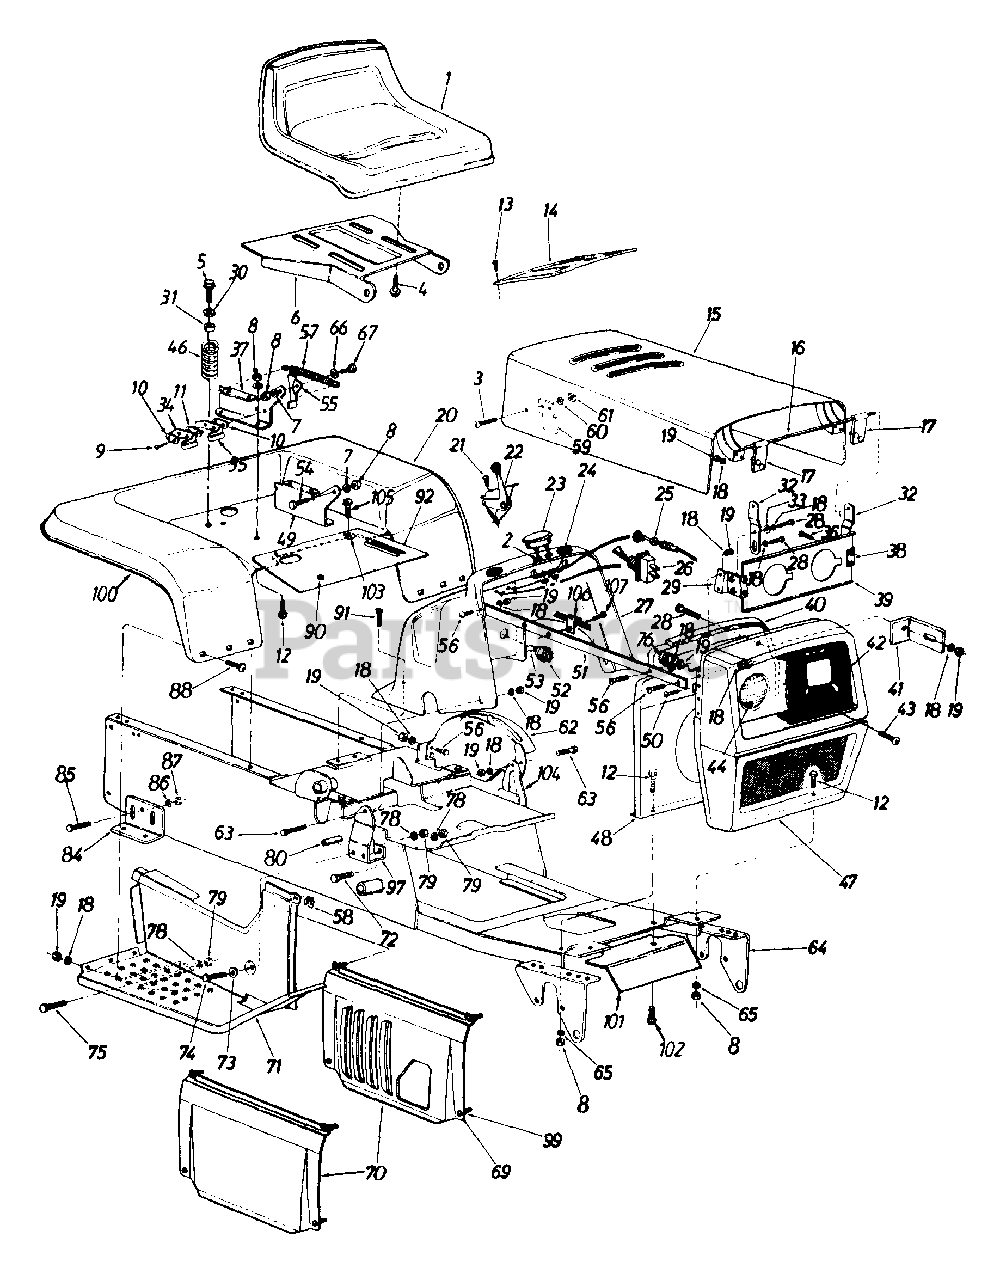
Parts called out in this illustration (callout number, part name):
2	L-Wash. .190" I.D.
3	Truss Hd. Mach. Scr. #10-24 x .38" Lg.
4	Hex Wash. Hd. Self-Tap Scr. 5/16-18 x .75" Lg.
5	Hex Wash. Hd. Tap Scr. 5/16-18 x .75" Lg.
6	Seat Pivot Bracket
7	L-Wash. 5/16" I.D.
8	Hex Nut 5/16-18 Thd.
9	Hex Wash. Hd. AB-Tap Scr. #8 x .5" Lg.
10	Insulator Plate
11	Insulator Boss Plate
12	Hex Bolt 5/16-18 x .75" Lg.
13	Self-Tap Oval Hd. Scr. 1/2" Lg.
14	Dash Panel Cover
15	Hood Ass'y.
17	Hood Hinge Ass'y.
18	L-Wash. 1/4" I.D.
19	Hex Nut 1/4-20 Thd.
20	Rear Fender
22	Throttle Control
23	Ammeter
24	Rubber Bumper
25	Choke Control
26	Light Switch
28	Hex Bolt 1/4-20 x .62" Lg.
29	Hood Support Brkt. Ass'y. - R.H.
30	Fl-Wash. .344" I.D. x .875"
34	Safety Switch
35	Safety Switch
36	Hex Bolt 1/4-20 x .38" Lg.
38	Hood Support Brkt. Ass'y. - L.H.
41	Heat Shield Brkt.
42	Head Lamp Bezel
43	Truss Mach. Scr. #10-24 x .50" Lg.
44	Head Lamp
46	Compression Spring 4.5" Lg.
50	Truss Mach. Scr. 1/4-20 x .75" Lg.
51	Grille Strap
52	Ignition Switch
53	Ignition Key
54	Shld. Bolt .437" Dia. x .162"
55	Seat Lift Bracket
56	Hex Bolt 1/4-20 x .75" Lg.
57	Extension Spring 5.31" Lg.
61	Hex Nut #10-24 Thd.
62	Speed Control Guide
63	Truss Mach. Scr. 1/4-20 x .75" Lg.
64	Frame Ass'y.
65	Bell-Wash. 5/16" I.D.
66	Spr. Wash. .445" I.D. x .75"
67	Shld. Bolt .437" Dia. x .268"
69	1/4-Turn Stud
70	Side Panel - R.H. & L.H.
71	Foot Step Panel Ass'y. - R.H.
72	Hex Bolt 3/8-16 x 1.00" Lg. Grade 5
73	Fl-Wash. .385" I.D. x .62" O.D.
74	Hex Bolt 3/8-16 x 3.00" Lg.
75	Hex Bolt 3/8-16 x 1.00" Lg. Grade 5
76	Snap Bushing
78	L-Wash. 3/8" I.D.
79	Hex Nut 3/8-16 Thd.
80	Spacer .375" I.D. x .62" O.D. x 2.00" Lg.
84	Transaxle Support Brkt.
85	Rd. Hd. Rib Neck Scr. 3/8-24
86	L-Wash. 3/8" I.D.
87	Hex Nut 3/8-24 Thd.
88	Carr. Bolt 1/4-20 x .50" Lg.
90	Snap Bushing
91	Fl. Hd. Self Tap Scr. 1/4-20 x .62" Lg.
100	Trim Strip 84" Lg.
103	Speed Nut #10-24 Thd.
104	Dash Panel Mtg. Brkt. - L.H.
105	Truss Mach. Scr. #10-24 x .5" Lg.
107	Self-Tap Scr. 5/16 x .5" Lg.
